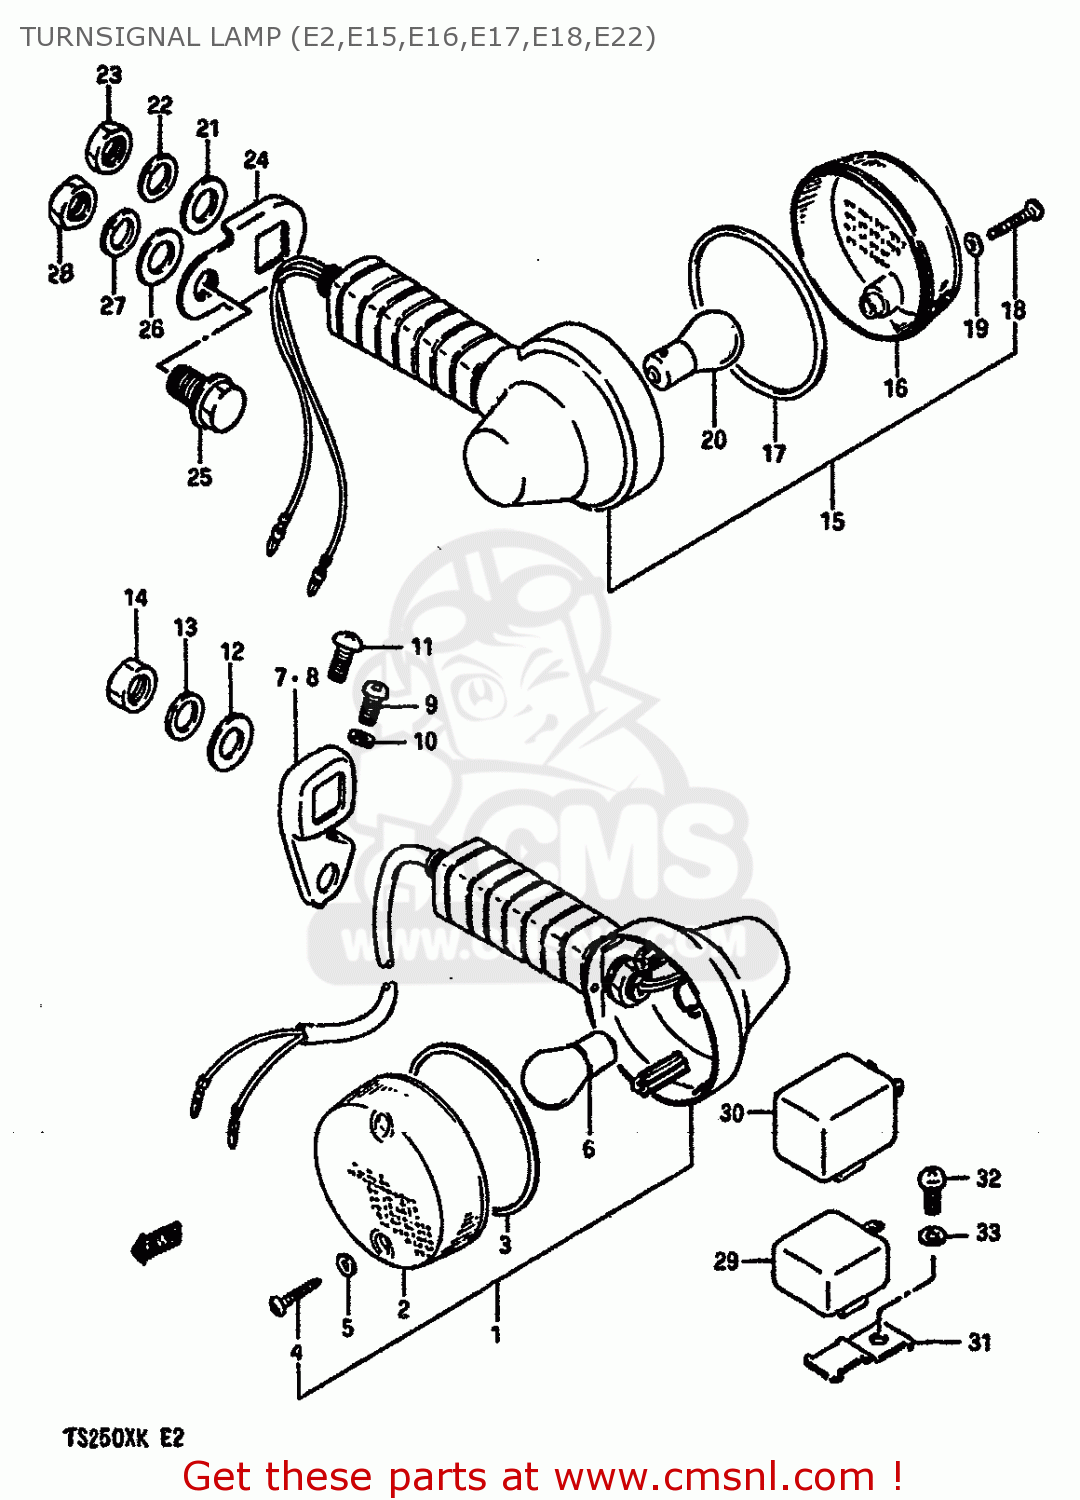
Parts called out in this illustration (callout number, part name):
1	LAMP ASSY,FRONT TURNSIGNAL
2	LENS
3	GASKET (NAS)
4	SCREW
5	GASKET (NAS)
6	BULB(12V21W)
7	BRACKET,FRONT RH
8	BRACKET,FRONT LH
9	SCREW
10	WASHER,LOCK
11	SCREW, FRONT & REAR
12	WASHER (12.5X26X1.6)
13	WASHER
14	NUT
15	LAMP ASSY,REAR TURNSIGNAL
16	LENS
17	GASKET (NAS)
18	SCREW
19	GASKET (NAS)
20	BULB(12V21W)
21	WASHER (12.5X26X1.6)
22	WASHER
23	NUT
24	BRACKET,REAR TURNSIGNAL
25	BOLT
26	WASHER (12.5X26X1.6)
27	WASHER
28	NUT
29	RELAY ASSEMBLY,TURN SIGNAL
30	RELAY ASSY,TUR
31	BRACKET,RELAY
32	SCREW
33	WASHER,LOCK
